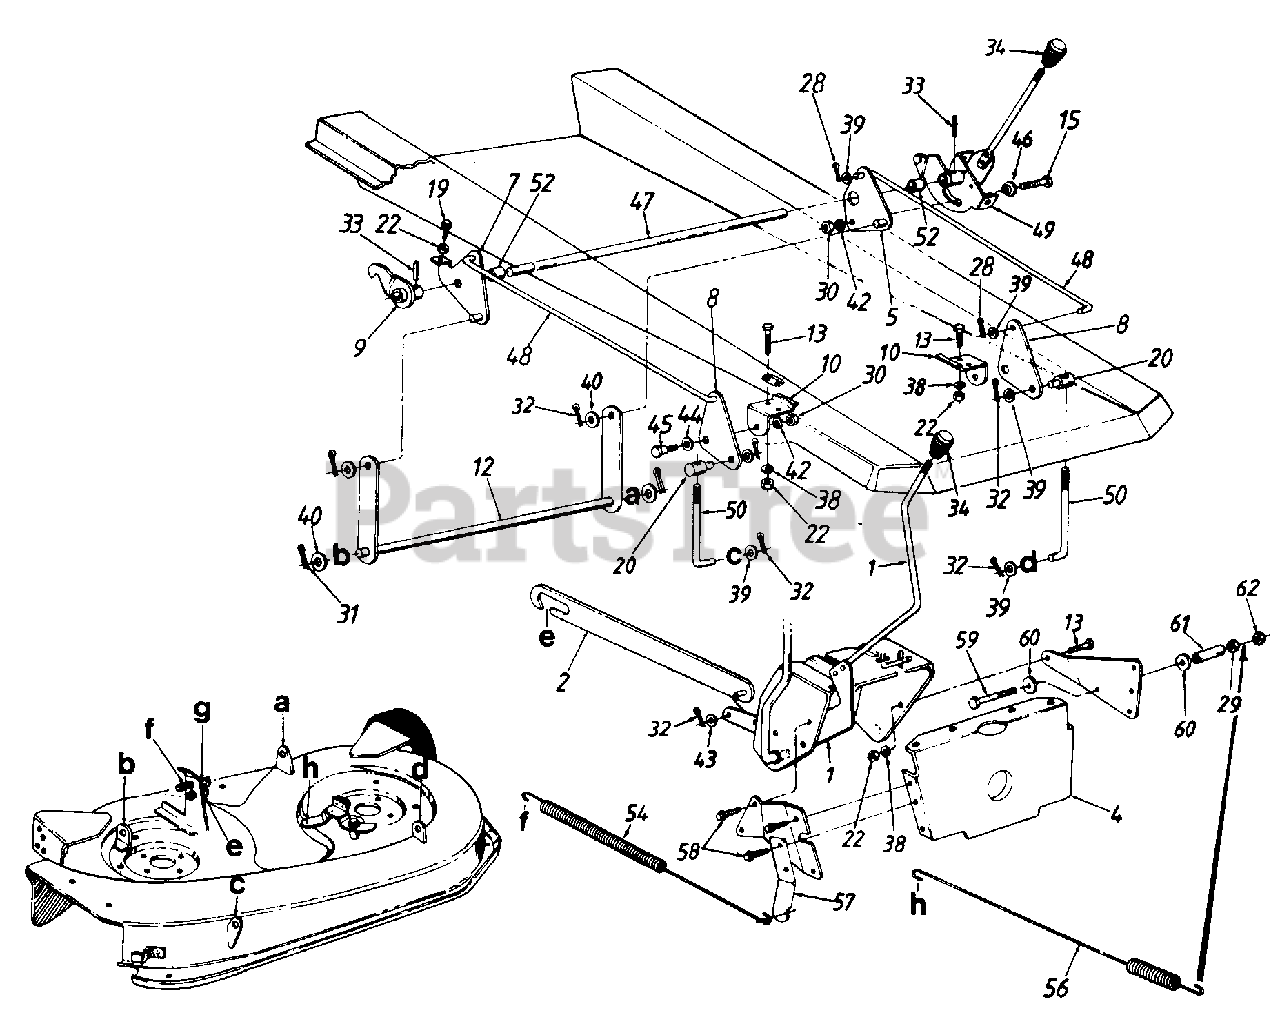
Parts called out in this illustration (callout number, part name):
7	Deck Lift Brkt. Ass'y.
8	Deck Lift Bracket
9	Deck Lift Float Brkt Ass'y.
10	Deck Lift Pivot Brkt.
12	Stabilizer Shaft Ass'y.
13	Hex Bolt 5/16-18 x .75" Lg.
15	Hex Bolt 3/8-16 x 1" Lg.
19	Hex Wash.-Tap Scr. 5/16-18 x 1.25" Lg.
20	Ferrule
22	Hex Nut 5/16-18 Thd.
28	Cotter Pin 3/32" Dia.
29	Hex Nut 1/4-20 Thd.
30	Hex Nut 3/8-16 Thd.
31	Internal Cot. Pin 1/2" Dia.
32	Int. Cot. Pins 3/8" Dia.
33	Spring Pin Spir. 1/4" Dia.
34	Knob
38	L-Wash 5/16" I.D.
39	Fl-Wash. .385 I.D. x .62
40	Fl-Wash. .635 I.D. x 1.12
42	L-Wash. 3/8" I.D.
43	Fl-Wash. .385 I.D. x .87 O.D.
44	Spring Washer .530 I.D.
45	Shld. Bolt .500" Dia. x .215"
46	Shld. Spacer .625" I.D.
47	Rear Hgt. Adj. Shaft
50	J-Bolt 5.4" Lg.
52	Spacer .885 I.D.
54	Ext. Spring 22.05" Lg.
56	Ext. Spring 15-5/8" Lg.
57	Spring Anchor
58	Hex Wash. Hd. AB-Tap Scr. 1/4 x .62" Lg.
59	Hex Bolt 1/4-20 x 2.5" Lg.
60	Fl-Wash. .25" I.D. x .93" O.D.
61	Spacer.255" I.D.
62	Hex L-Nut 1/4-20 Thd.
